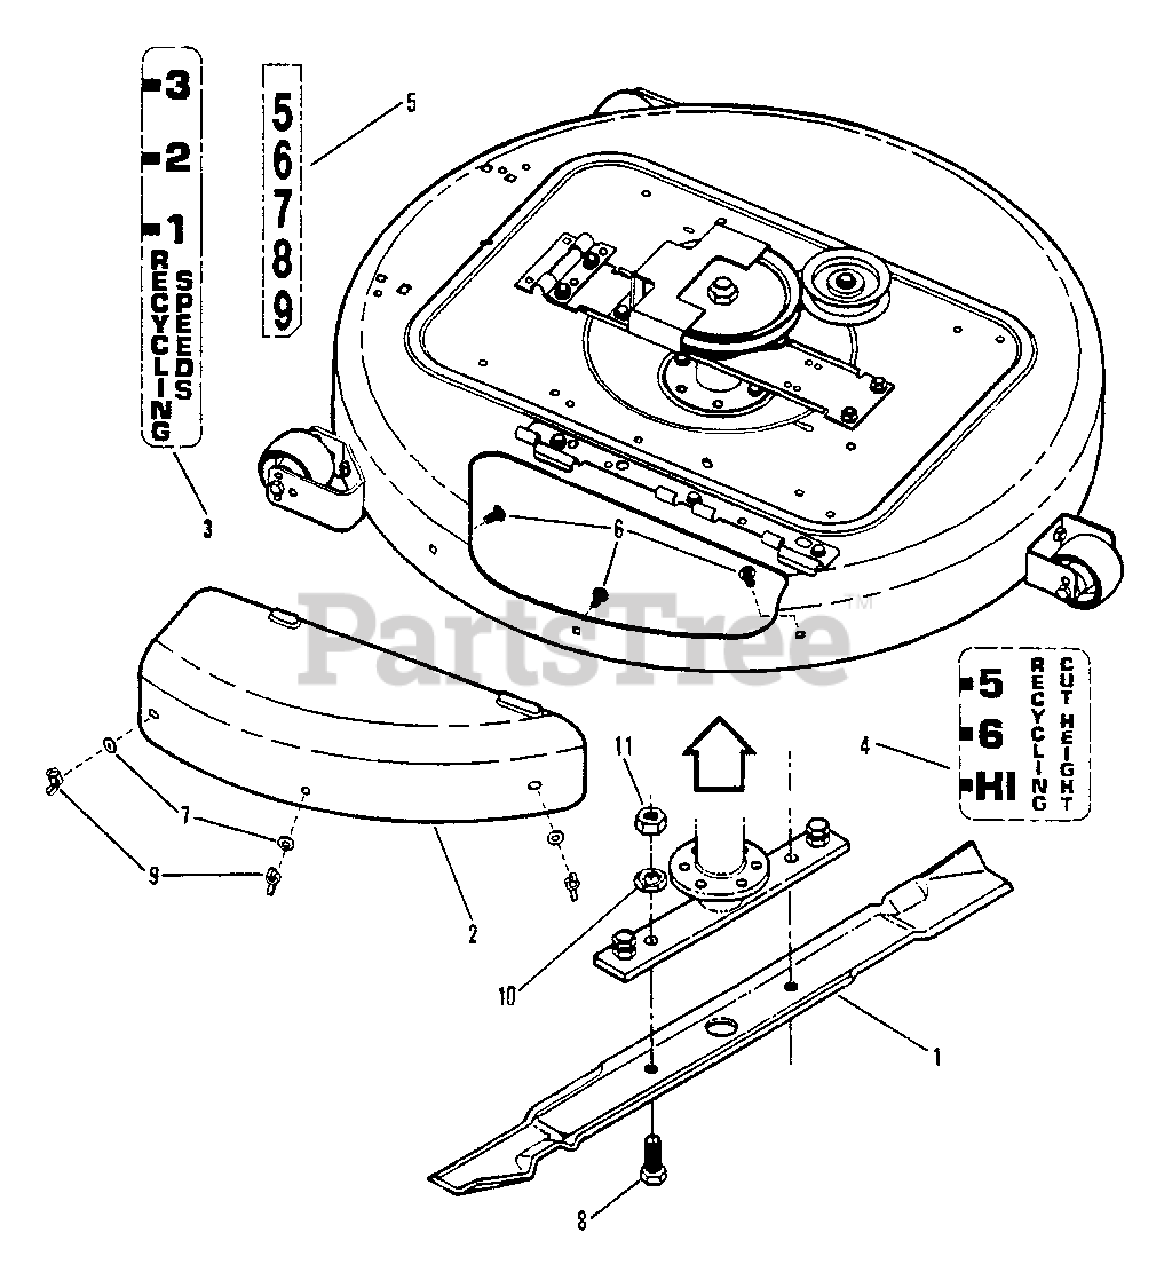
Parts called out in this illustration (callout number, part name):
1	BLADE, 33" Recycling
2	COVER, 33" Side Chute
3	DECAL, Recy. Ground Speed
4	DECAL, Recycling Ht. of Cut
5	DECAL, Cut Height
6	BOLT, 5/16-18 x 3/4" Short Neck Carriage, Grade 5
7	WASHER, 5/16" Flat
8	SCREW, 1/2-20 x 1" Hex Head Cap, Grade 5
9	WING-NUT, 5/16-18
10	WASHER, 1/2" Internal Tooth
11	NUT, 1/2-20 Hex Jam
